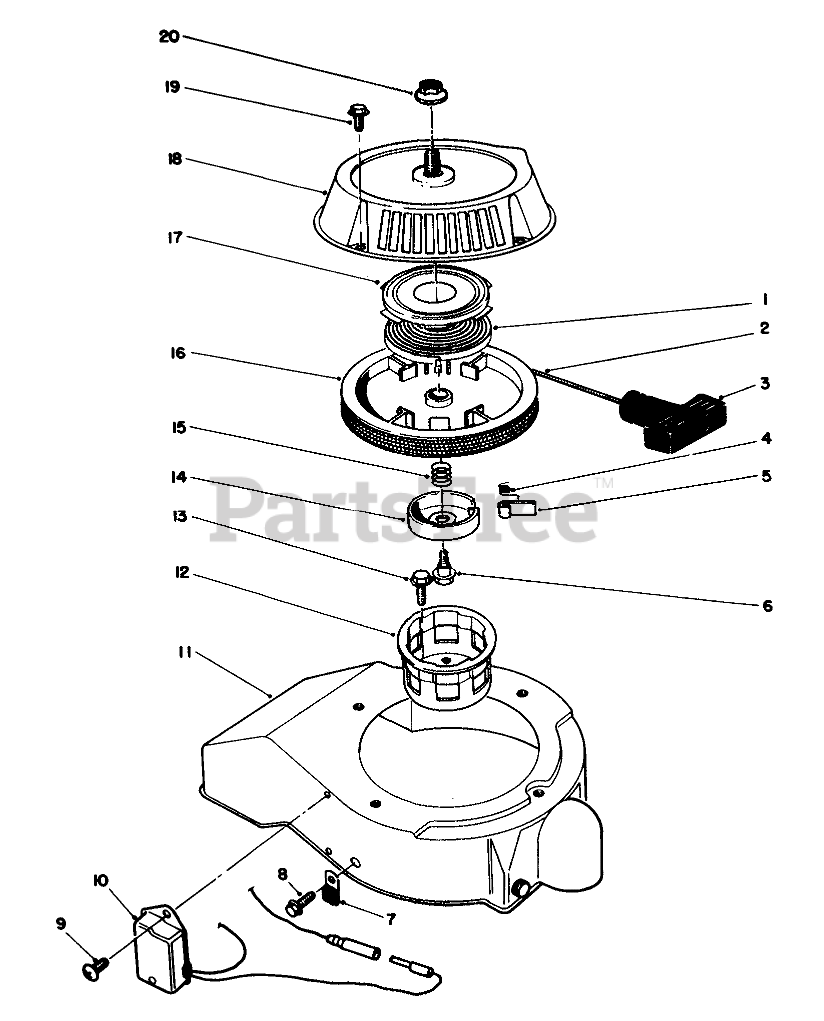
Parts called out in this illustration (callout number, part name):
1	Spring-Recoil (Incl. Ref. #17)
2	ROPE-STARTER
3	HANDLE-RECOIL
4	SPRING
7	CLAMP
9	SCREW
10	MODULE
11	SHROUD
12	CUP - STARTER
14	RETAINER
15	SPRING
17	Retainer-Recoil Spring
18	RECOIL CASE
19	MOUNTING SCREW
20	NUT (F/W & PPP)
